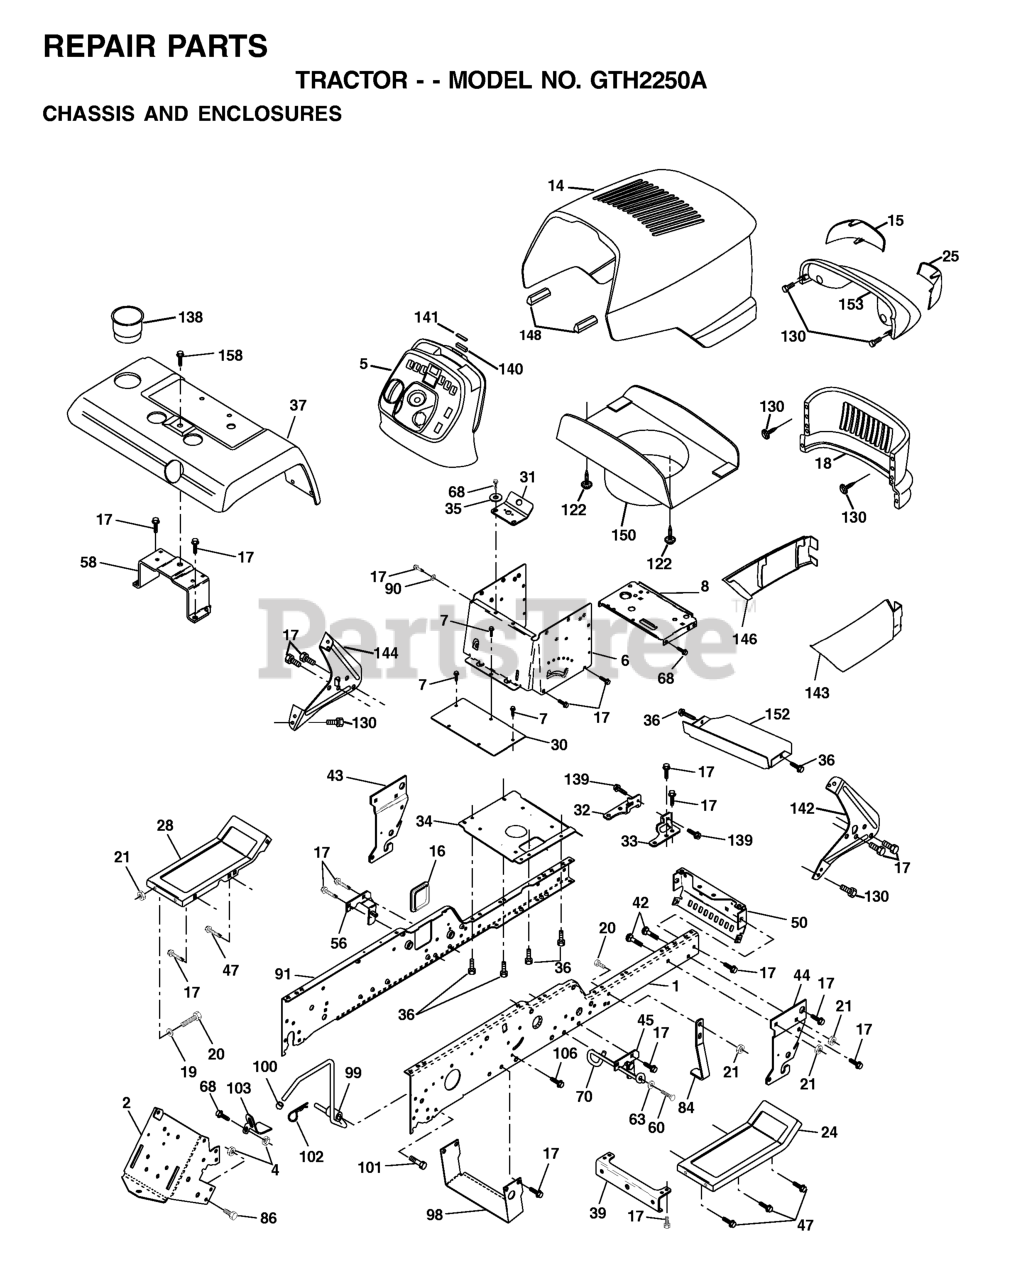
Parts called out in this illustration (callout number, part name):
2	DRAWBAR, GT
4	Nut, Lock Hex 7/16 Unc
5	DASH.STEALTH.YTGT.2CYL.BLK
6	DASH VGT, LOWER
7	SCREW
8	SUPPORT, BATTERY
14	HOOD ASM.
15	LENS LH
16	COVER ACCESS
17	SCREW 3/8-16X3/4
18	GRILLE
19	WASHER
20	BOLT
24	FOOTREST RH
25	LENS RH
28	FOOT REST LH
30	SADDLE.HYDRO.95
31	BRACKET SUPT 1-PC VGT STEERING
34	PLATE ASM ENG CHASSIS
35	WASHER
36	SCREW 5/16"
39	BRACKET AXLE, FRONT
42	BOLT D
43	FRONT SUSPENSION BRKT LH
44	FRONT SUSPENSION BRKT RH
45	BRACKET SUSP RH
47	SCREW LT
50	BRACKET, CHASSIS FRONT
56	BRACKET ASM, SUSP CHASSIS
58	BRACKET ASM, FENDER
60	SCREW.3/8-16
63	WASHER
68	Screw 5/16-18 x 1/2 Hex, Self Tapping 5/16-18 x 1/2
84	MOWER STOP
86	BOLT
90	LOCKWASHER
99	ROD ASMBLY BYPASS
100	PLUNGER CAP
101	SCREW LT
102	RETAINER M
103	BRACKET LOCK BYPASS
106	SCREW
122	SCREW.HEX.WS.HD.8-18 X 7/8
130	SCREW
139	BOLT, SHOULDER 5/16-18
140	MAGNET STEALTH
141	STRIKER PLATE
142	BRACKET DASH STEALTH(R)
143	SKIRT GRILLE RH
144	BRACKET DASH STEALTH LH
146	SKIRT GRILLE LH
148	EXTRUSION BUMPER (3 2) (2 2)
150	DUCT HEAT HOOD
152	BROWNING SHIELD
158	SCREW 3/8-16X1/2
